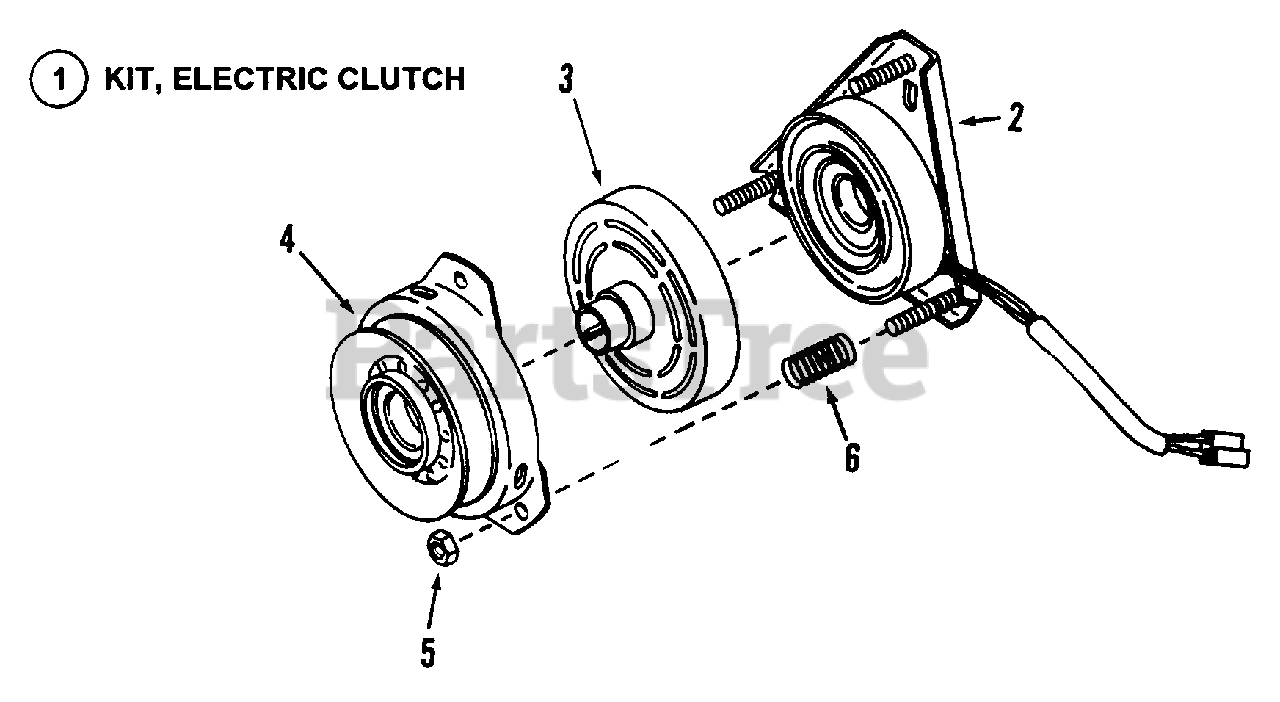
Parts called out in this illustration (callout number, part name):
1	KIT, Electric Clutch
2	FIELD COIL
3	ROTOR
4	ASSEMBLY, Arm-Pulley
5	NUT, 3/8-24 Hex Nylok
6	COIL SPRING
